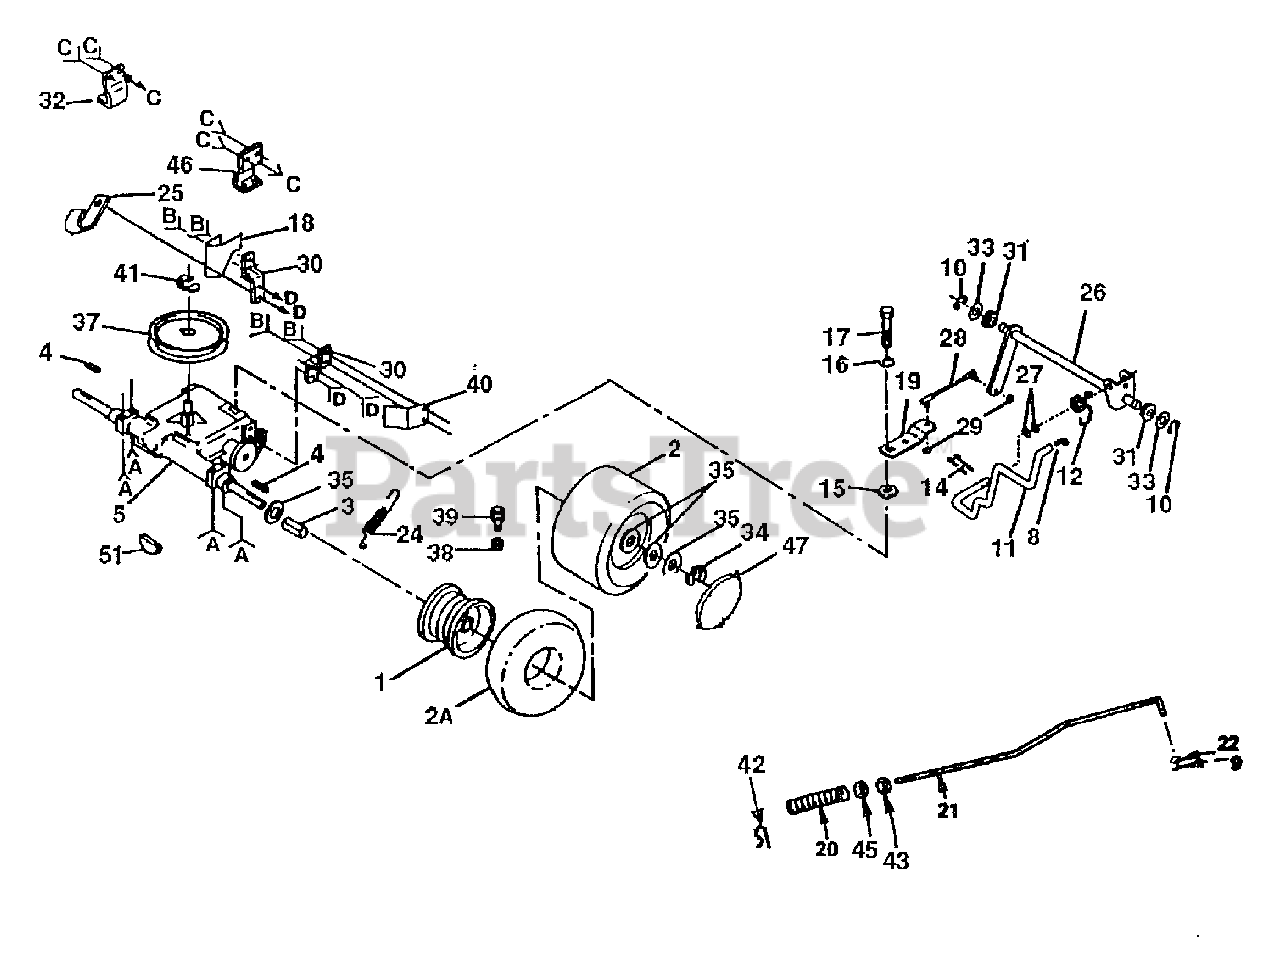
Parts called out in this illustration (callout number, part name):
1	Rim Assembly, Rear
2	Tire
2A	Tube, Tire
3	Spacer, Split
4	Key, Square 1/4 x 2
5	Transaxle, 6 Speed, Peerless Model No. 820-016
8	Knob, Control
9	Pin, Cotter 1/8 x 3/4
10	Ring, Klip
11	Rod, Shifter
12	Spring, Torsion
14	Pin, Cotter 1/8 x 1
15	Washer, Shift Plate
16	Washer 9/32 x 3/4 x 16 Gauge
17	Bolt, Hex 1/4-28 x 3/4 x 16 Grade 8
18	Keeper, Belt, Transaxle, L.H.
19	Arm, Shift
20	Spring, Rod, Brake
21	Rod, Brake
22	Washer 13/32 x 13/16 x 16 Gauge
24	Spring, Brake Return
25	Clip
26	Shaft, Arm Shifter
27	Washer 17/32 x 3/4 x 16 Gauge
28	Rod, Tie
29	Nut 1/4-28
30	Strap, Torque
31	Bushing, Steering Rod
32	Bracket, Transaxle, L.H.
33	Washer 21/32 x 1-1/4 x 16 Gauge
35	Washer 1-1/32 x 1-5/8 x 16 Gauge
37	Pulley, Transaxle
38	Cap, Valve
39	Stem, Valve
40	Keeper, Belt, Transaxle, R.H.
41	Ring, Retainer
42	Clip, Hairpin
43	Nut, Hex, Jam 3/8-16
45	Locknut, Hex Washer Insert 3/8-1
46	Bracket, Transaxle, R.H.
47	Cover, Wheel
51	Key, Woodruff
